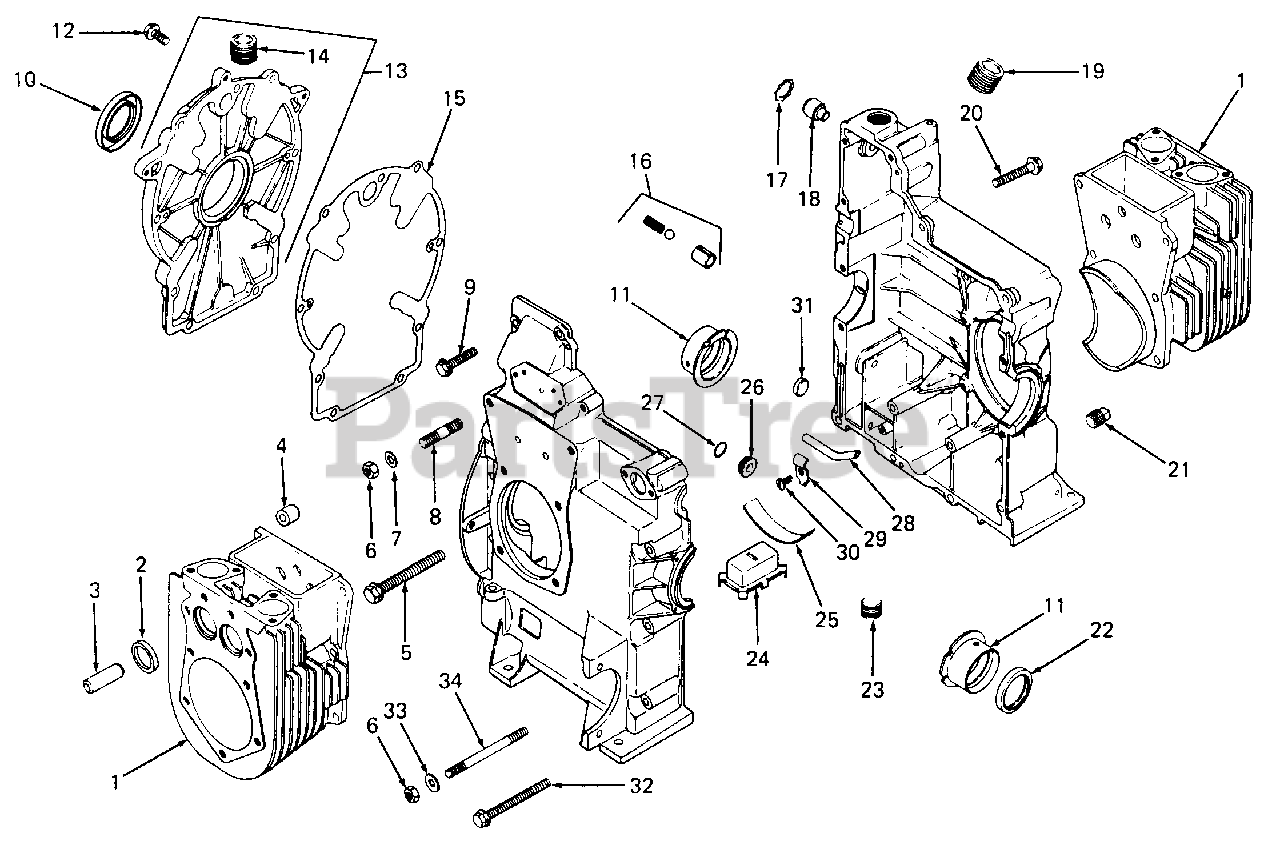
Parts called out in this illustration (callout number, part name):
1	Kit, Cylinder
2	Insert, Valve Seat
3	Guide, Valve
4	Bushing, Locating
5	Screw, Hex Flange, 3/8-16 X 3.62 Lg
6	Nut, Hex, 5/16-18
7	Washer, Flat
8	Stud, Step, 5/16-18 X .75, 3/8-16 X .62, 2.0 Lg
9	Screw, Hex Flange, 5/16-18 X 1.5 Lg
10	Seal, Rear Oil
11	Bearing, Sleeve (Std)
12	Screw, Wash Hd, 5/16-18 X 1.0 Lg
13	Kit, Closure Plate
14	Plug, Hex Ctsk, 1/8 NPTF
15	Gasket, Closure Plate
16	Kit, Oil Relief
17	Ring, Retaining
18	Shaft, Governor
19	Plug, Pipe, 1/16 X 27 NPTF
20	Screw, Hex Flange, 5/16-18 X 2.0 Lg
21	Plug, Bottom Drain, 3/8
22	Seal, Front Oil
23	Plug, Hex Ctsk, 3/8 NPTF
24	Housing, Oil Pickup
25	Clamp, Spring
26	Plug, 3/4 OD
28	Tube, Oil Pickup
30	Screw, Hex Wash Hd, #10-32 X 7/16 Lg
31	Plug, Cup, 5/16
32	Screw, Hex Flange, 5/16-18 X 3.5 Lg
33	Washer, Plain
34	Stud, 5/16-18 X 4.12 Lg
